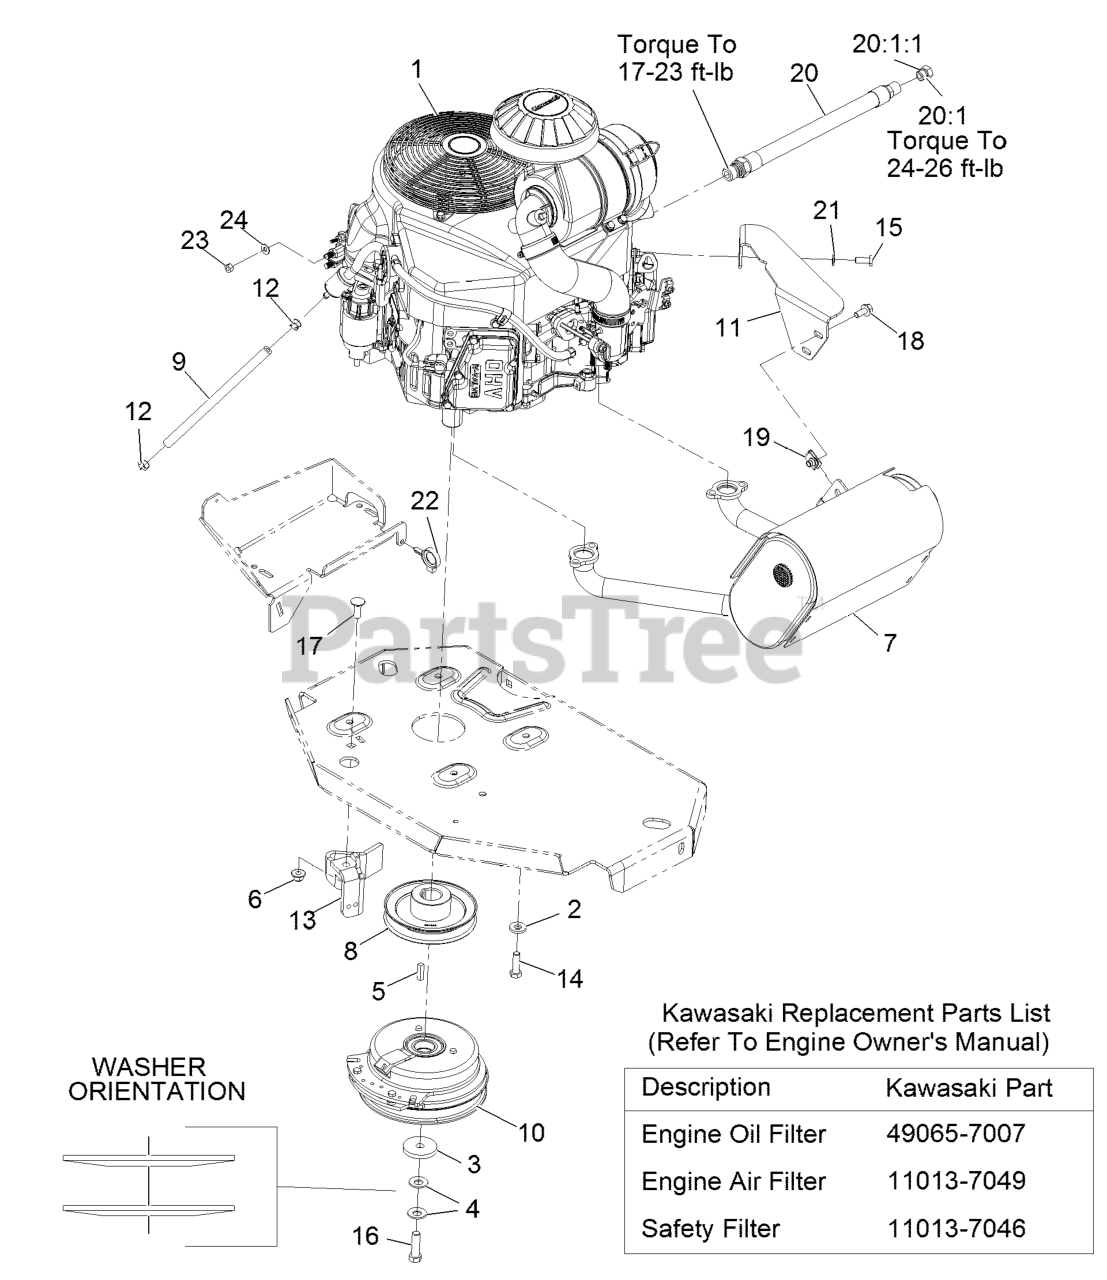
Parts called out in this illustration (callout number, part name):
1	Engine-Kawasaki
2	WASHER-BELLEVILLE
3	WASHER-CLUTCH
4	WASHER-SPRING
6	NUT-HF, NI
7	MUFFLER
8	SHEAVE-PUMP, DRIVE
9	HOSE-FUEL
11	BRACKET-MUFFLER
12	CLAMP-HOSE
13	CLUTCH-ANCHOR
14	SCREW-HH
15	SCREW-HH
16	SCREW-HH 7/16-20 X 1 1/2 W/LOCTITE
17	SCREW-CARR
18	SCREW-HHF
20	ENGINE OIL DRAIN HOSE ASM
20:1	PLUG-HH
20:1:1	O-RING
21	WASHER-SPRING
22	CLAMP-HOSE
23	NUT-HEX
24	WASHER-FLAT
